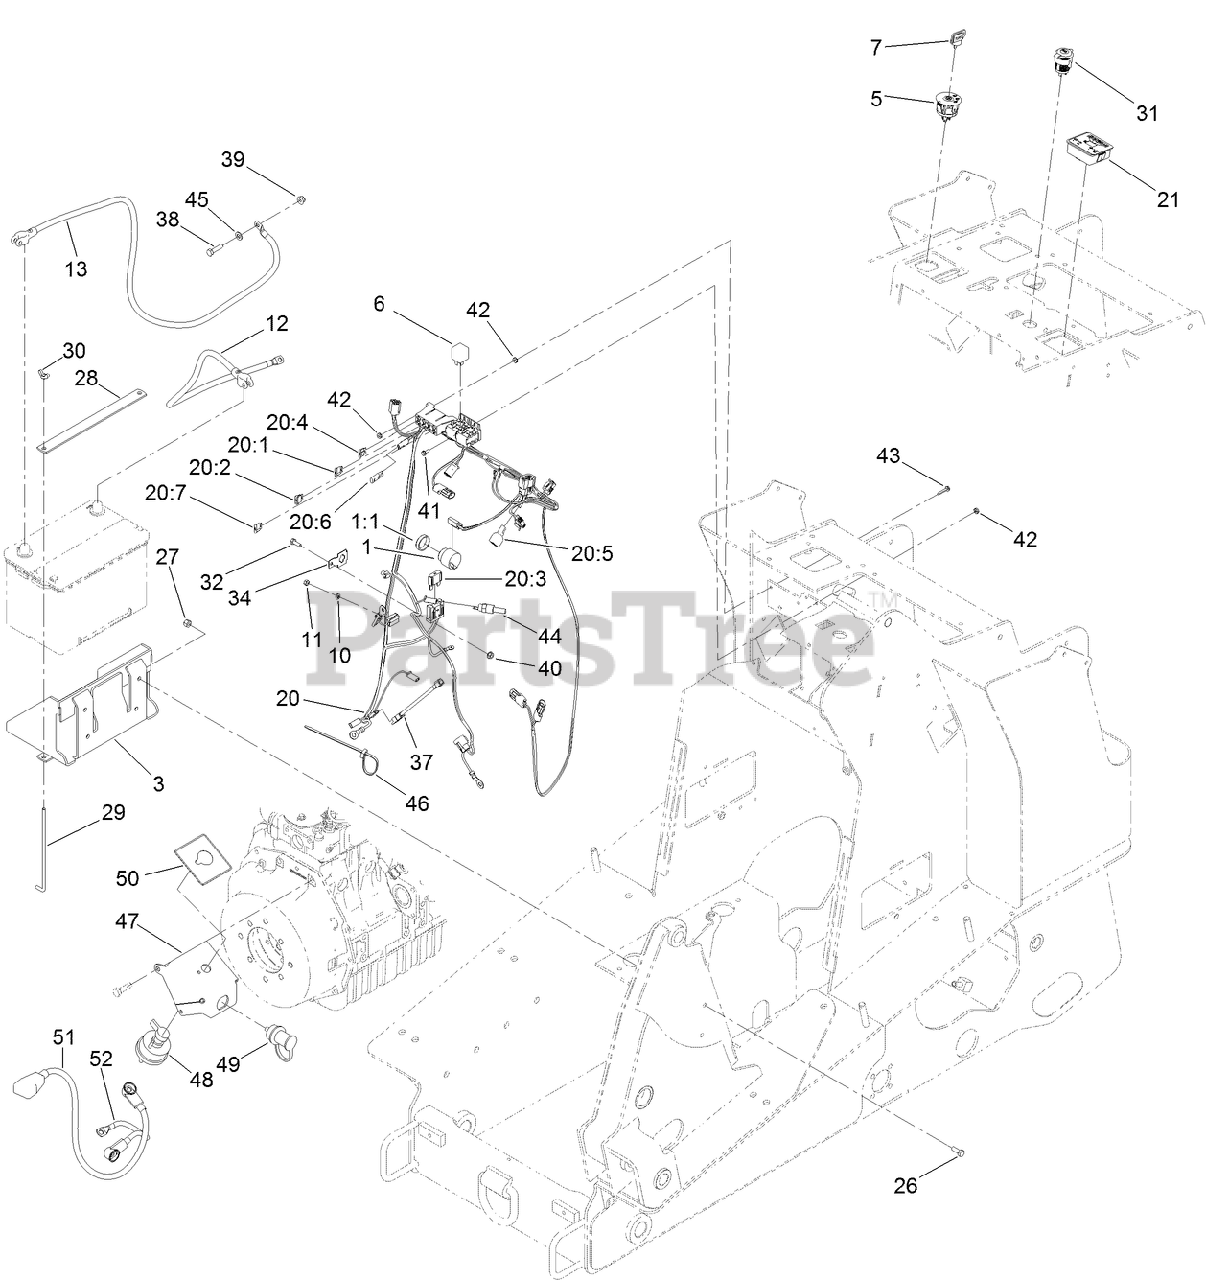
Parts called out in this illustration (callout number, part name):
1	AUDIO ALARM ASM
1:1	NUT-PLASTIC, KNURLED
3	TRAY-BATTERY
5	SWITCH-IGNITION
7	KEY-IGNITION
10	WASHER-LOCK, SPRING
11	NUT-HEX
12	CABLE-BATTERY, POSITIVE
13	CABLE-NEGATIVE
20	HARNESS-WIRE
20:1	FUSE-BLADE, 10 AMP
20:2	FUSE-BLADE, 15 AMP
20:3	FUSE-BLADE, 50 AMP
20:4	FUSE-BLADE, 7.5 AMP
20:6	CAP-PLUG
20:7	FUSE-BLADE, 20 AMP
21	MODULE-HOUR METER
26	SCREW-HH
27	NUT-LOCK, NI
28	STRAP-HOLD DOWN, BATTERY
29	ROD-HOLD DOWN, BATTERY
30	Wingnut
31	RECEPTACLE-12V
32	SCREW-HH
34	CLIP-FUSE
37	HARNESS-LINK, FUSIBLE
38	SCREW-HH
39	NUT-HF, NI
40	NUT-HF
41	SCREW-HWH
42	NUT-KEPS
43	SCREW-HWHTF
44	SWITCH-TEMP
45	WASHER-PLAIN
46	TIE-CABLE
47	MOUNT-REMOTE TERMINAL
48	SWITCH-DISCONNECT, MASTER
49	STUD-JUMPER, POSITIVE
50	DECAL-BATTERY DISCONNECT
51	CABLE-BATTERY, POSITIVE
52	CABLE-BATTERY, POSITIVE
